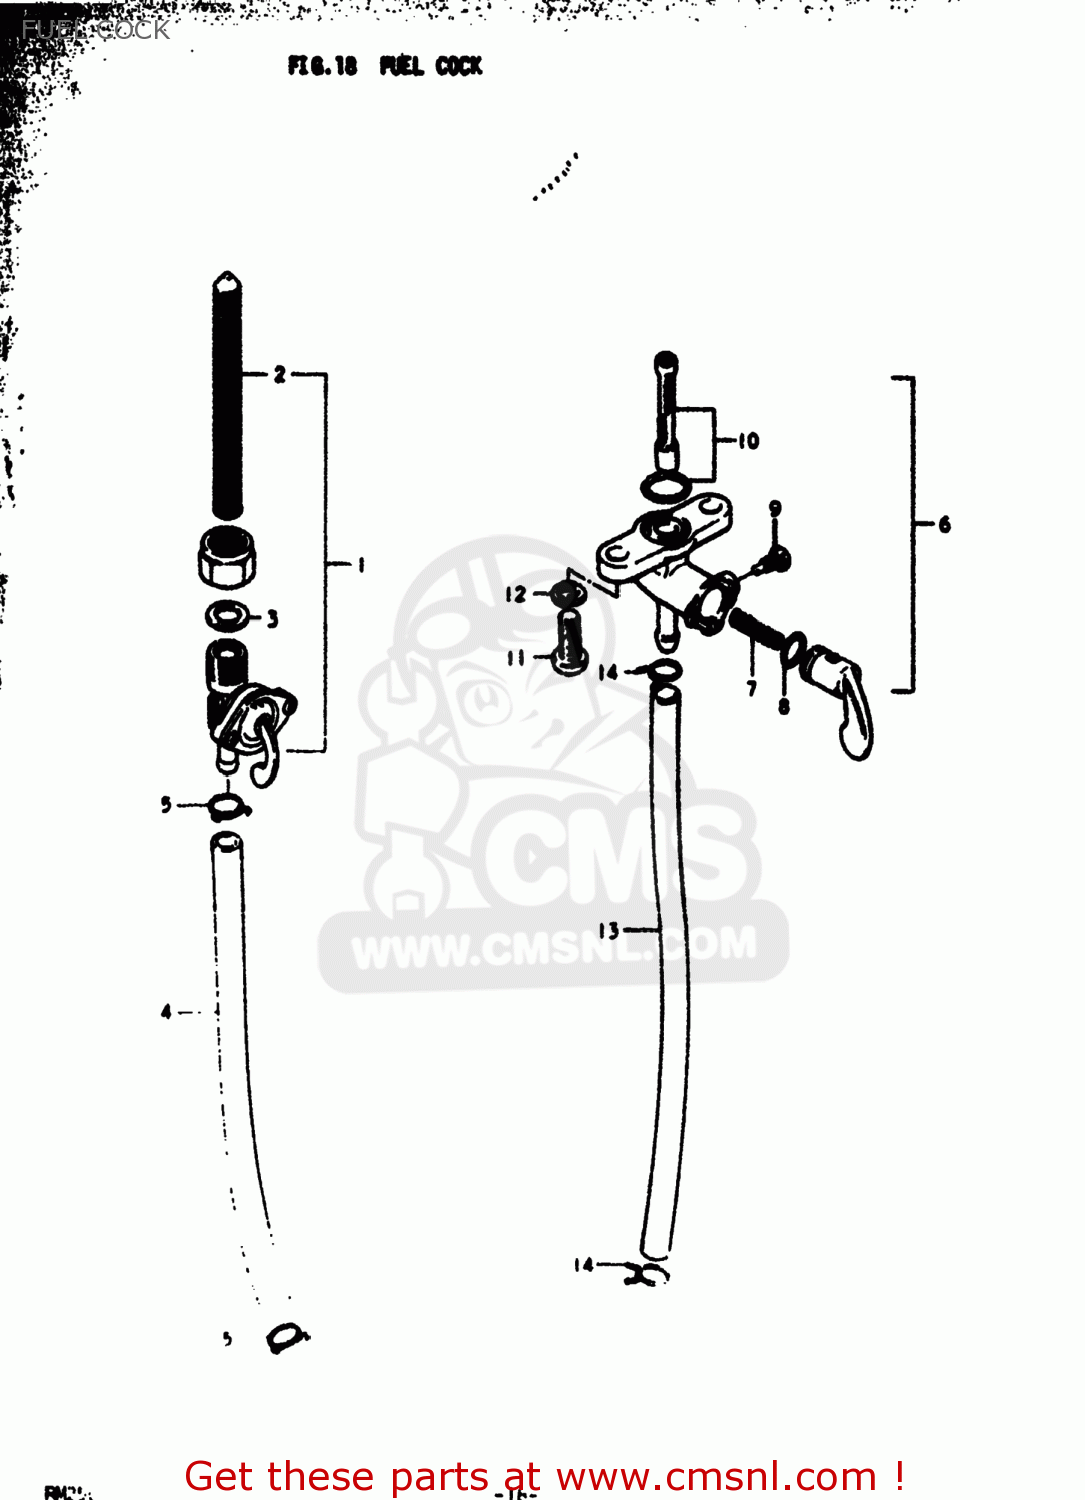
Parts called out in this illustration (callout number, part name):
1	COCK ASSY,FUEL
2	FILTER,FUEL
3	GASKET,FUEL COCK (NAS)
4	HOSE
5	CLIP
6	COCK ASSEMBLY,FUEL
7	SPRING,FUEL COCK VALUE
8	O RING,LEVER
9	SCREW
10	FILTER SET FUEL
11	SCREW
12	LOCK WASHER
13	HOSE
14	CLIP
